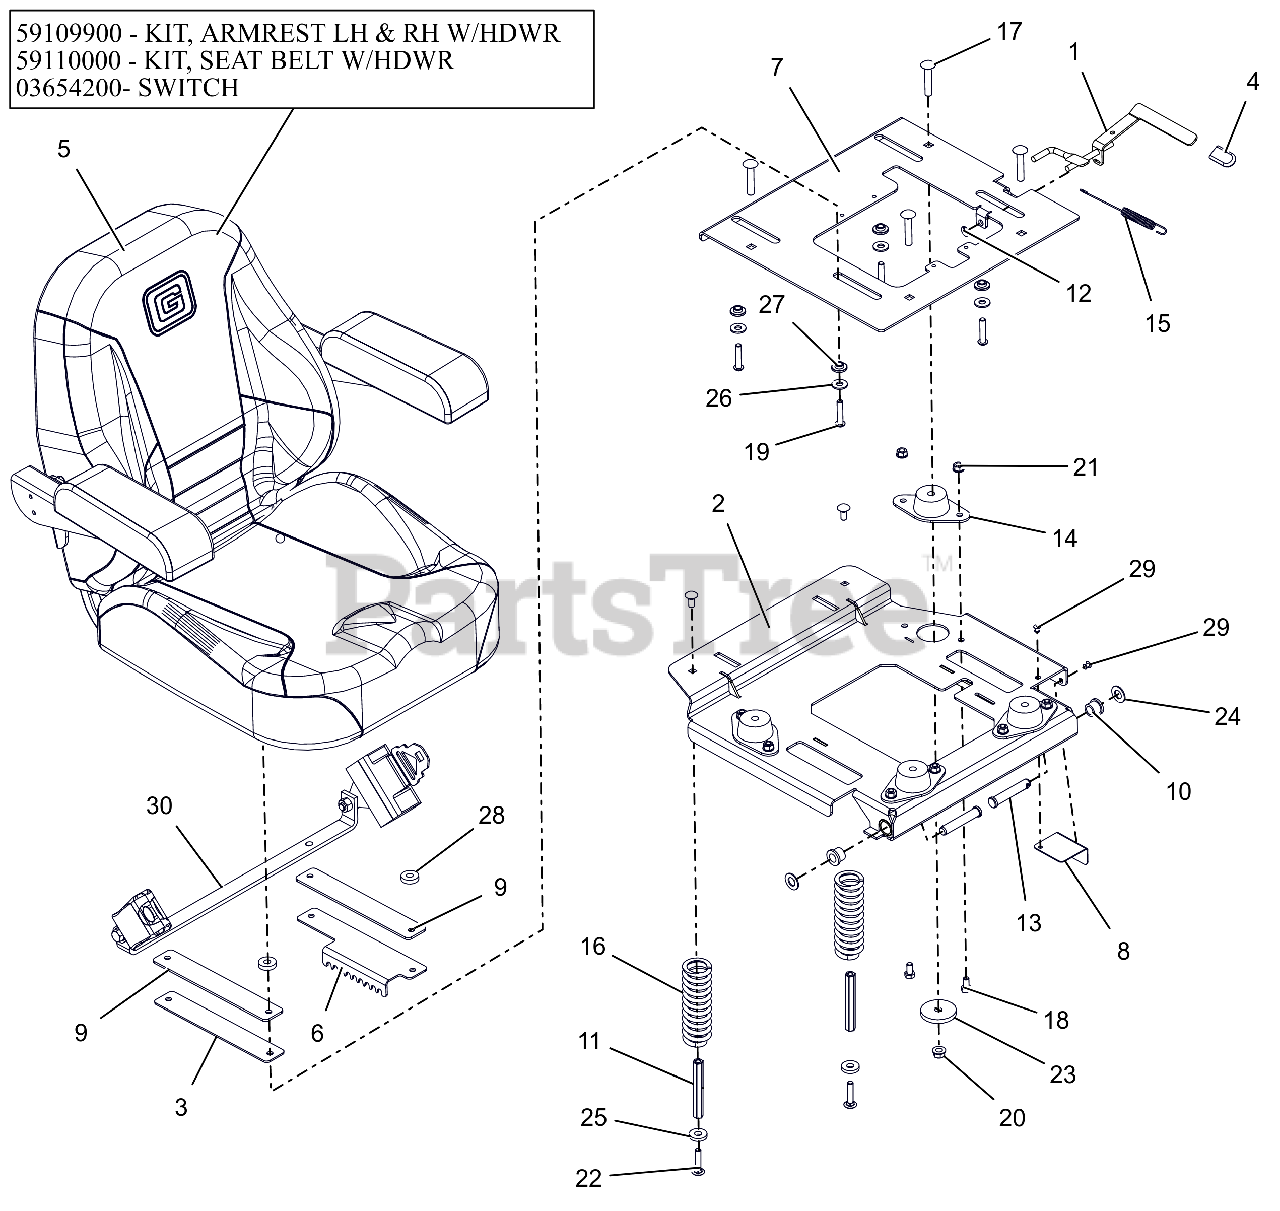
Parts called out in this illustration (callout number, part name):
1	WLDMT, SEAT SLIDE LEVER
2	WLDMT, ISO MTG PLATE (BLACK)
3	PLATE, ADJUSTABLE SEAT SLIDE
4	GRIP, SEAT LEVER, GREY
5	KIT, LH&RH ARM REST-05007300
5	KIT-SEAT BELT REPLACE-05007300
5	SWITCH- SEAT
6	PLATE, HD SEAT ADJUSTMENT
7	PLATE, SEAT MOUNTING (ISO KIT) (RED)
8	GUARD, SEAT FAN (SH)(BLACK)
9	SPCR, SEAT
10	BSHG, FLG .516X.750X.625X.937
11	NUT, COUPLING 5/16X18 X 3.75
12	NUT-PUSH .312
13	PIN, SLIC-.500X42.70X2.31 -ZC
14	MOUNT, FAIL-SAFE COMPRESSION
15	SG-TENS .06X.482X5.35
16	SPRING, COMPRESSION SEAT 224LB
17	BLT,RHSSN.375-16X2.00 G5 ZCC
18	BLT, HEX .31-18X.625 G5 ZCC
19	SCR,BTNHD .31-18X1.50 ZCC
20	NUT-LK-CTR-FLG .375-16 GF ZCC
21	NUT,LK-CTR-FLG .31-18 GF ZCC
22	BLT,RHSN .31-18X1.50 G5 ZCC
23	WSHR-FL-STL 0.406X2X0.25 ZCC
24	WSHR, FLT .531X1.00X.063 ZCC
25	WSHR, FLT .406X1.00X.188 ZCC
26	WSHR,FLT .375X.875X.083 ZCC
27	BSHG-FLG .325X.499X.3X.875
28	WSHR, FLT .390X1.00X.250 ZCC
29	RIVET, .1875 AL/AL .126-.250
30	KIT-SEAT BELT REPLACE-05007300
